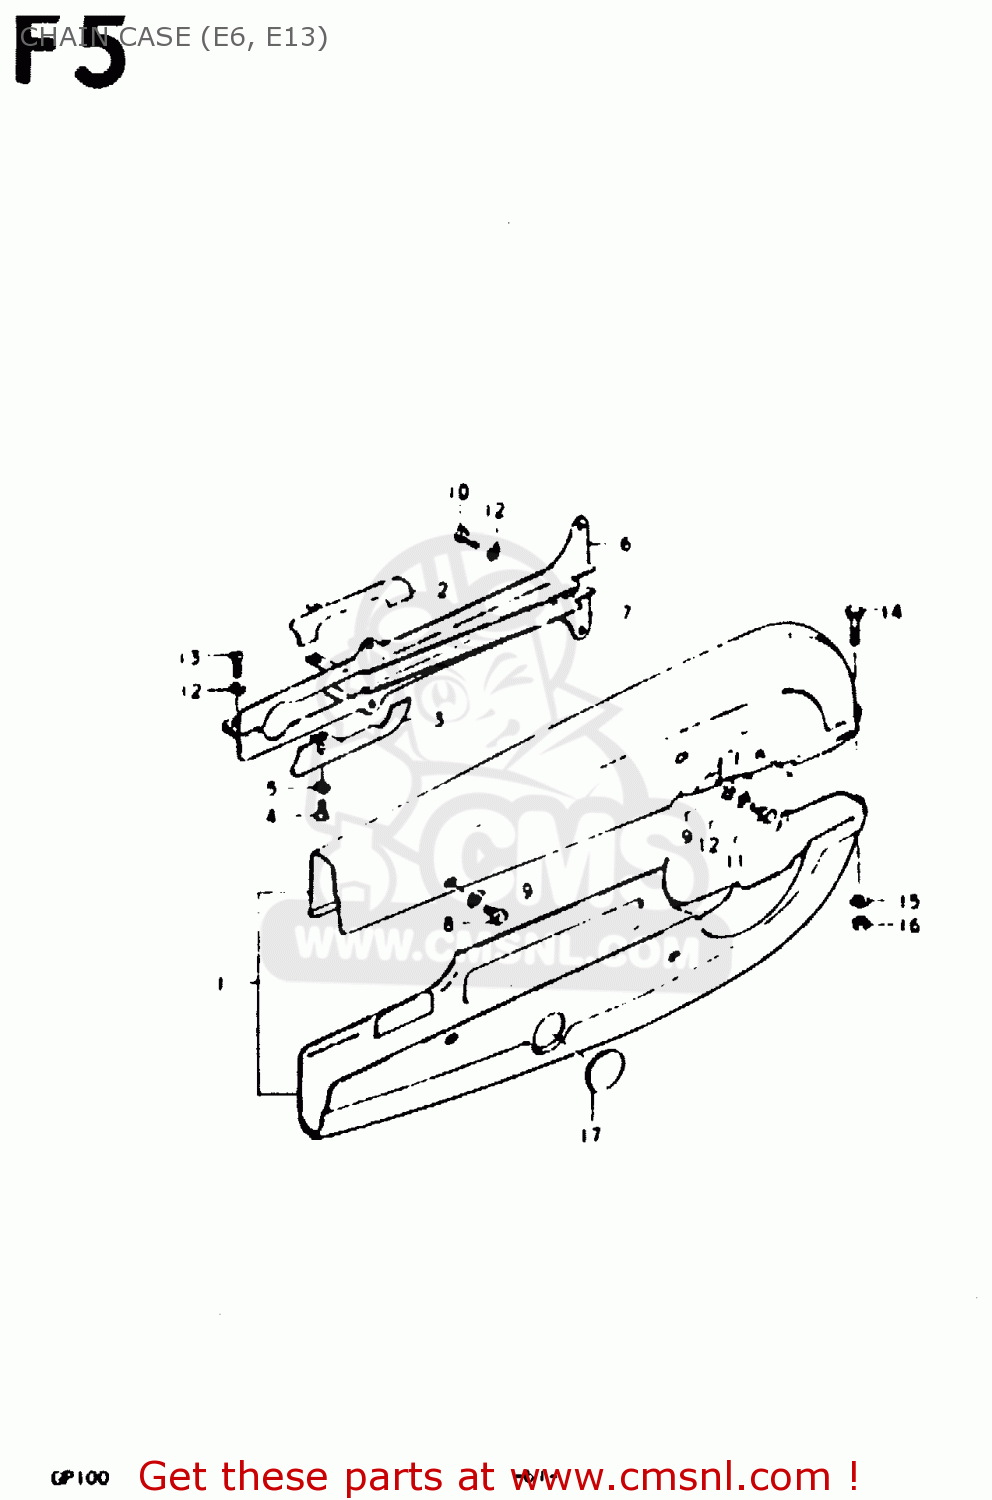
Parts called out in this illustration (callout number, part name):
1	CHAIN CASE SET
2	PLATE, FITTING INNER
3	PLATE, FITTING INNER LOWER
4	SCREW
5	LOCK WASHER
6	PLATE, FITTING UPPER
7	PLATE, FITTING LOWER
8	BOLT(6X6)
9	WASHER
10	BOLT
11	BOLT(6X14)
12	LOCK WASHER
13	SCREW
14	BOLT
15	WASHER
16	NUT
17	CAP(OD:40)
